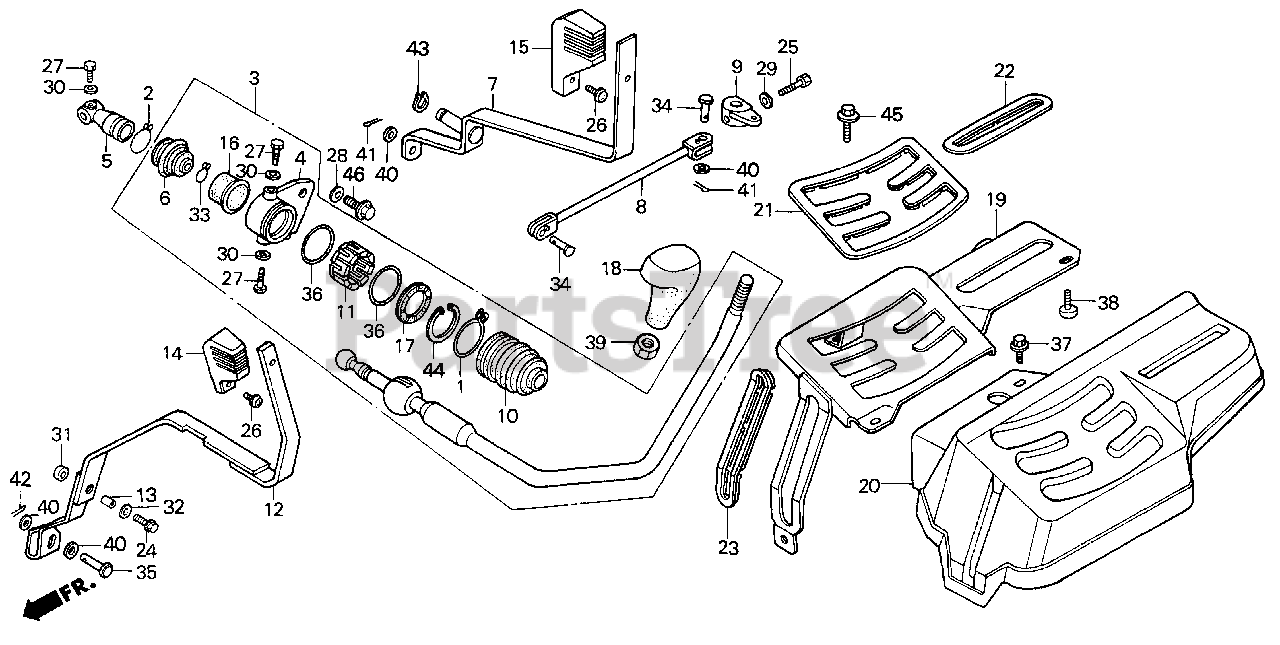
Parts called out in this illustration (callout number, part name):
1	CLIP, AIR IN. TUBE
2	CLIP, MUFFLER GASKET SETTING
3	LEVER ASSY., CHANGE
4	HOLDER, CHANGE LEVER
5	ARM, CHANGE LEVER
6	BOOT, CHANGE LEVER (A)
7	LEVER, P.T.O. SHIFT
8	ROD, P.T.O. CHANGE
9	ARM, P.T.O. CHANGE
10	BOOT, CHANGE LEVER (B)
11	SEAT, CHANGE LEVER BALL
12	LEVER, AUXILIARY CHANGE
13	COLLAR (8X12X10.2)
14	KNOB B, CHANGE LEVER *YR161* (ORANGE)
15	KNOB C, P.T.O. LEVER *Y121* (YELLOW)
16	DUST SEAL B, CHANGE
17	STOPPER, CHANGE LEVER BALL
18	KNOB, SHIFT LEVER
19	GUIDE, L. CONTROL
20	PANEL, L. CONTROL *R136* (DIANA RED)
21	TRIM, LEVER GUIDE (B)
22	TRIM, LEVER GUIDE (A)
23	TRIM, SHIFT GUIDE
24	BOLT, FLANGE (8X35)
25	BOLT, SPECIAL (6X21)
26	SCREW, HINGE PATCH
27	BOLT, SPECIAL (8X24)
28	WASHER, PLAIN (10MM)
29	WASHER, CONICAL SPRING (6MM)
30	WASHER, CONICAL SPRING (8MM)
31	WASHER, PLAIN (8X24X6)
32	WASHER, PLAIN (8X23X3.2)
33	CLIP, AIR HOSE (16MM)
34	PIN, P.T.O. CHANGE ROD
35	PIN, FLAT (6X27.5)
36	O-RING (35X3)
37	BOLT-WASHER (6X16)
38	SCREW, TAPPING (6X12)
39	NUT, HEX. (12MM)
40	WASHER, PLAIN (6MM)
41	PIN, COTTER (1.6X25)
42	PIN, COTTER (1.6X25)
43	CIRCLIP (OUTER) (12MM)
44	CIRCLIP (INNER) (40MM)
45	BOLT, FLANGE (8X16)
46	BOLT, FLANGE (10X28)
